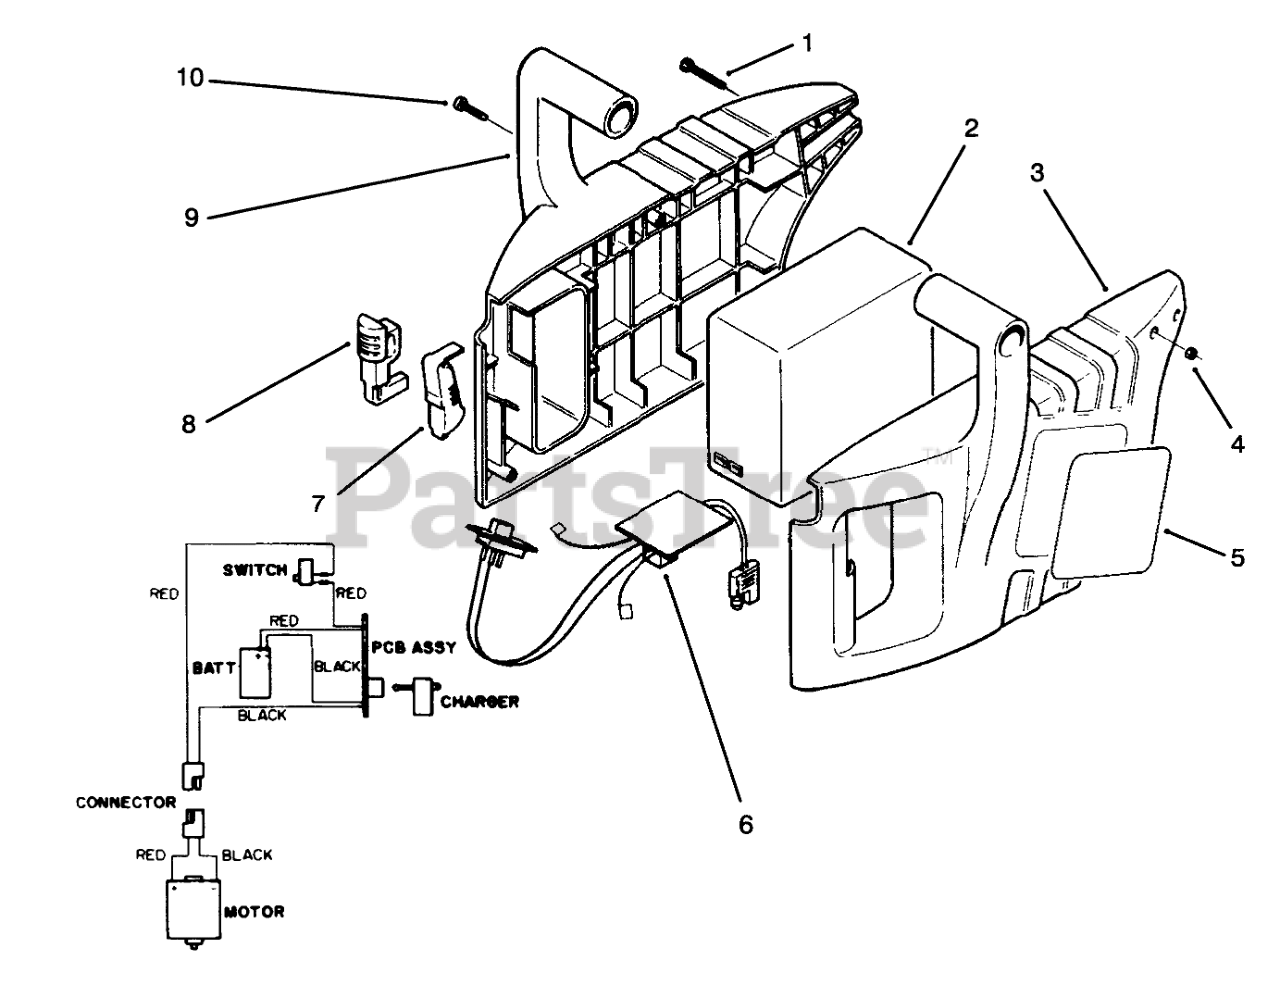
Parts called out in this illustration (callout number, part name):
1	SCREW-PPH
2	BATTERY
3	RH BATTERY CASE/HNDL
4	NUT-HEX
5	DECAL - 7" TRIM
6	ASSY-PCB
7	TRIGGER
8	TRIGGER LOCK
9	LH BATTERY CASE/HNDL
10	Screw
